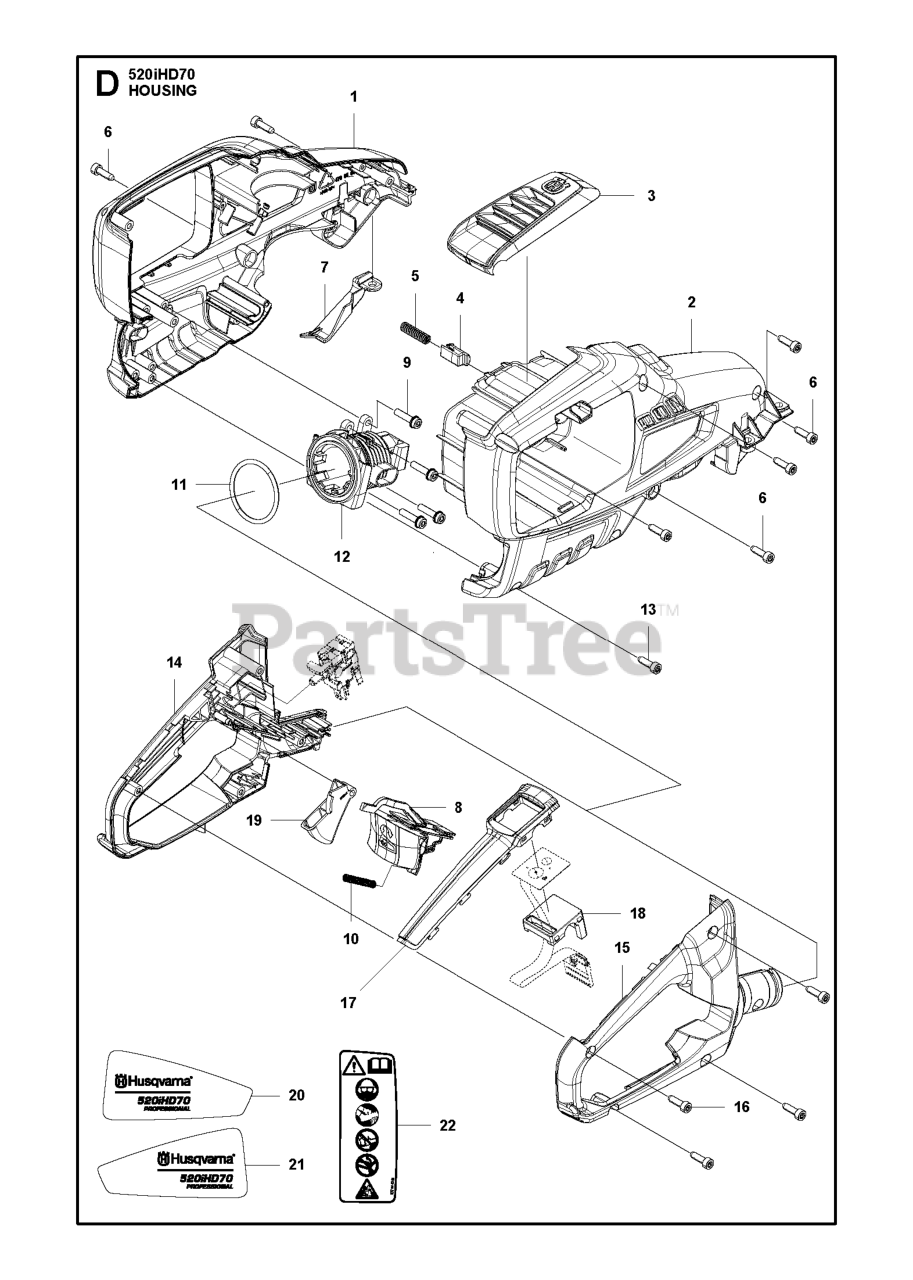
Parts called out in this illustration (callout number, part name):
1	CHASSIS LEFT
2	CHASSIS RIGHT
3	COVER CHASSIS
4	PUSH BUTTON
5	SPRING
7	COVER WIRING
8	LOCKING BUTTON
9	SCREW IHSCFT
10	RECOIL SPRING RECOIL SPRING RE
12	HANDLE HOLDER
13	SCREW
14	REAR HANDLE LEFT
15	REAR HANDLE RIGHT
16	SCREW
17	FRAME KEYPAD
18	BRACKET KEYPAD
19	THROTTLE CONTROL
